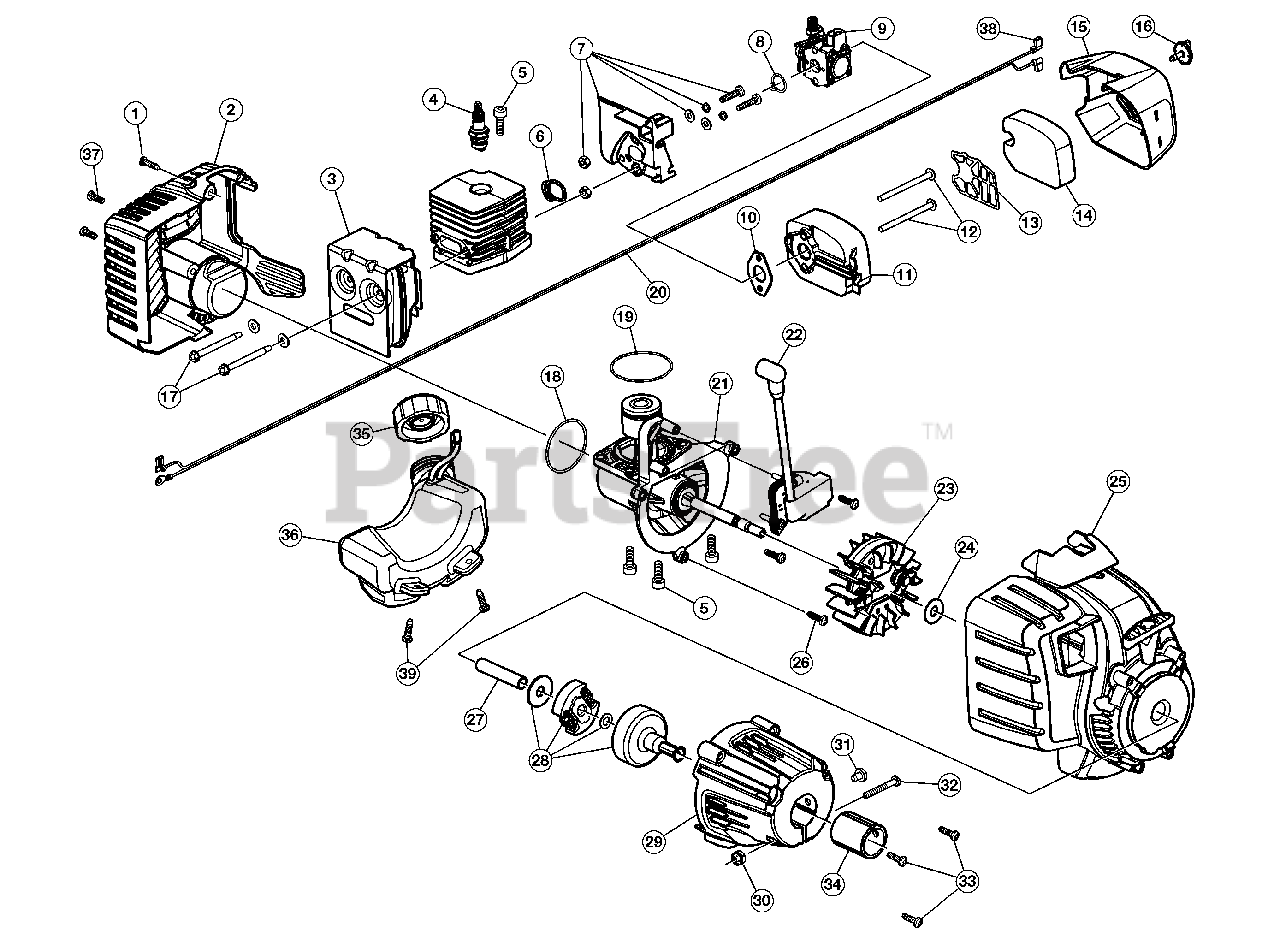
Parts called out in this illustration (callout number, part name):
2	Housing, Rear (Incl. 1, 18 and 37)
3	Muffler
4	Spark Plug
6	O-Ring
7	Insulator Assembly (Incl. 6 and 8)
8	O-Ring
9	Carburetor
10	Gasket
11	Air Cleaner Base
14	Filter
15	Air Cleaner Cover
17	Muffler Screw
18	O-Ring
19	O-Ring
20	Lead Wire
21	Shortblock (Incl. 4, 5, 19, 22, 23, 24)
22	Module
23	Flywheel
24	Washer
25	Housing, Starter
26	Screw
27	Spacer
28	Clutch Assembly
29	Clutch Cover
32	Screw
34	Spacer, Rubber
35	Fuel Cap
36	Fuel Tank (Incl. 35 and 39)
37	Screw
39	Fuel Tank Screw
